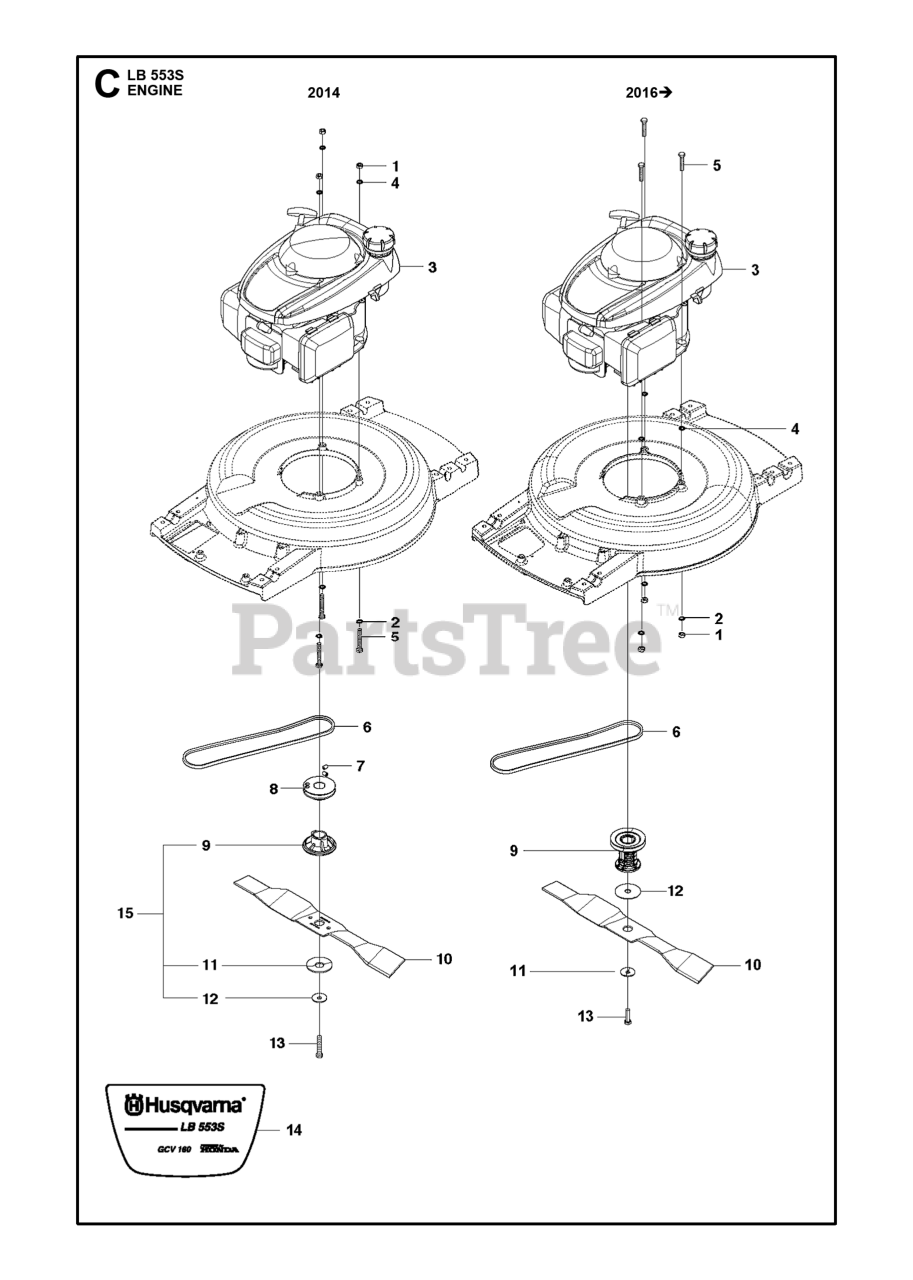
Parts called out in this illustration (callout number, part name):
1	LOCKNUT M8
2	WASHER BRB 8.4X17
4.1	WASHER BRB 8.4X17
6	BELT
8	PULLEY M53S / M48S
9.1	BLADE SUPPORT
12.2	Washers
13.1	BOLT M53 / M48
